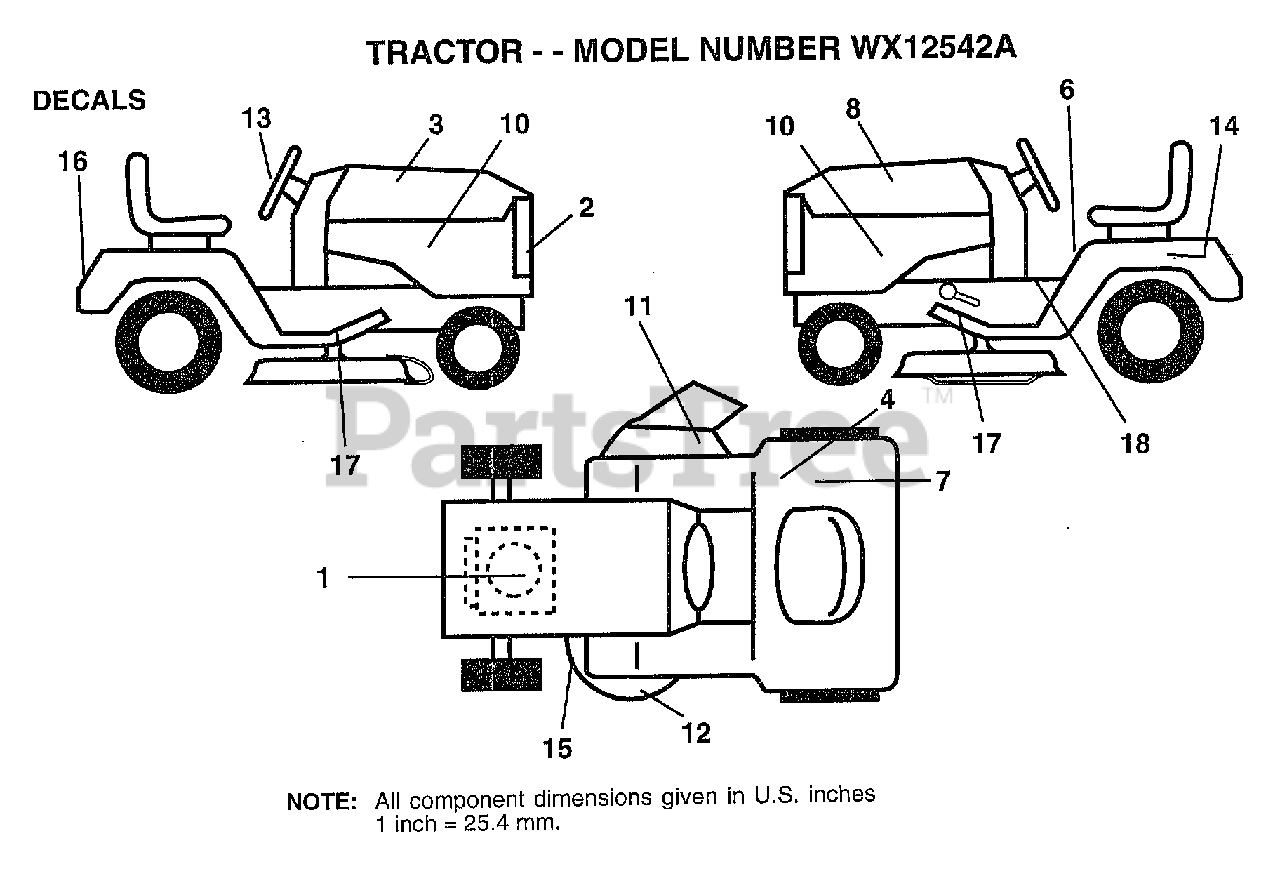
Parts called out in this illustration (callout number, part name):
1	DECAL, HP ENGINE
2	DECAL.GRILL
3	DECAL.HD.STRIP.RH
4	DECAL.EURO.ST.CE.
6	DECAL.READ.O.MANU
8	DECAL.HD.STRIP.LH
10	DECAL.PNL.SIDE
11	DECAL.DANGER.CUTF
12	DECAL.MOWER
13	DECAL.WHL.STRG.
14	DECAL.BATRY.3-3908
15	DECAL
16	DECAL.FENDER
17	"PAD,FOOTREST"
18	DECAL BRAK PARK
